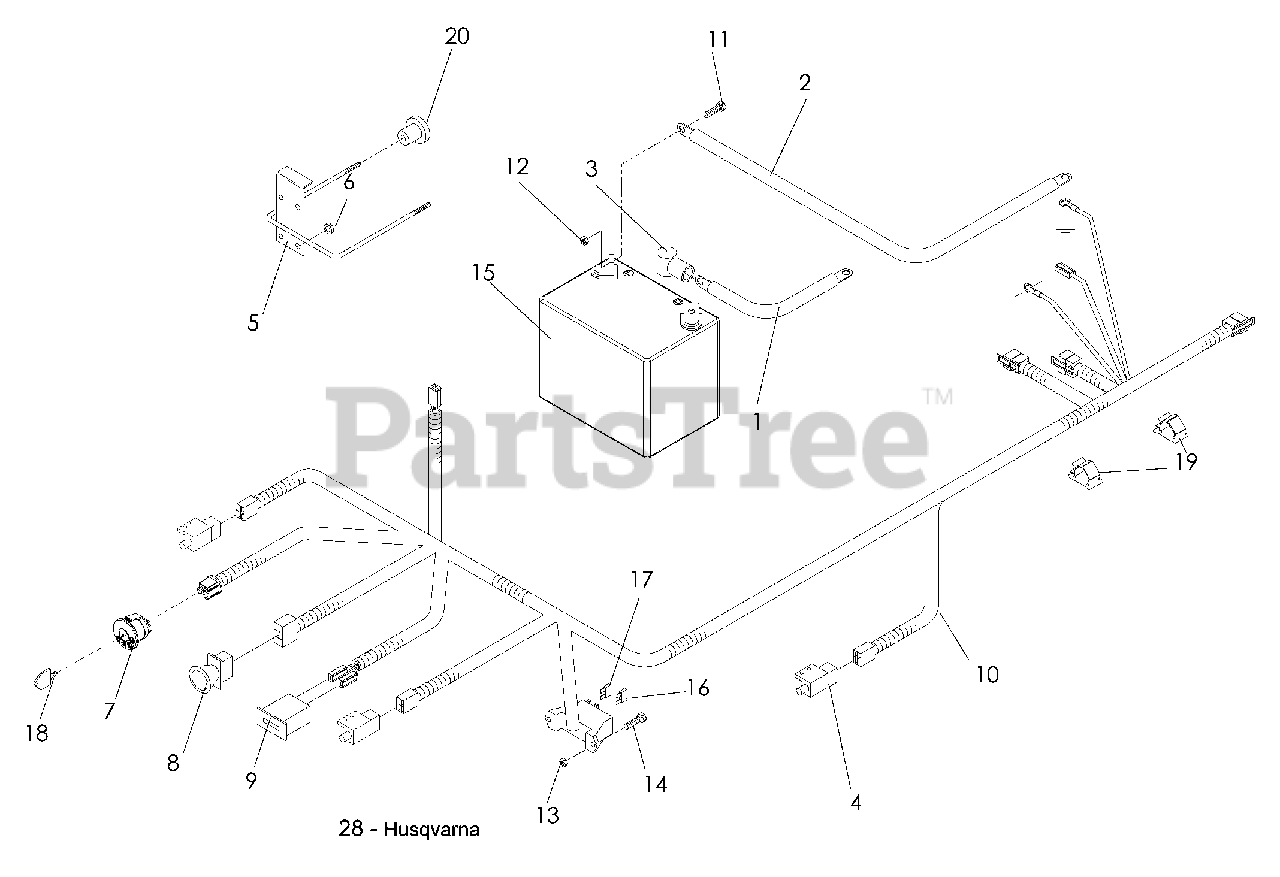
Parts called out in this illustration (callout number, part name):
1	CABLE, POSITIVE
2	CABLE, NEGATIVE
4	SWITCH, INTERLOCK
5	BATTERY HOLD DOWN
7	SWITCH, IGNITION
8	SWITCH, PTO
9	METER, HOUR
10	FRAME HARNESS
11	HCS 5/16-18 x ¾
12	NUT 5/16-18 HEX NYLOC
13	NUT 10-24, NYLOC
14	SCREW 10-24 x 7/8
15	BATTERY, DRY
16	FUSE, 7.5 AMP, 32V, ATO
17	FUSE, 20 AMP, 32 V, ATO
18	KEY, PADDED
19	CLIP, PUSH MOUNT
